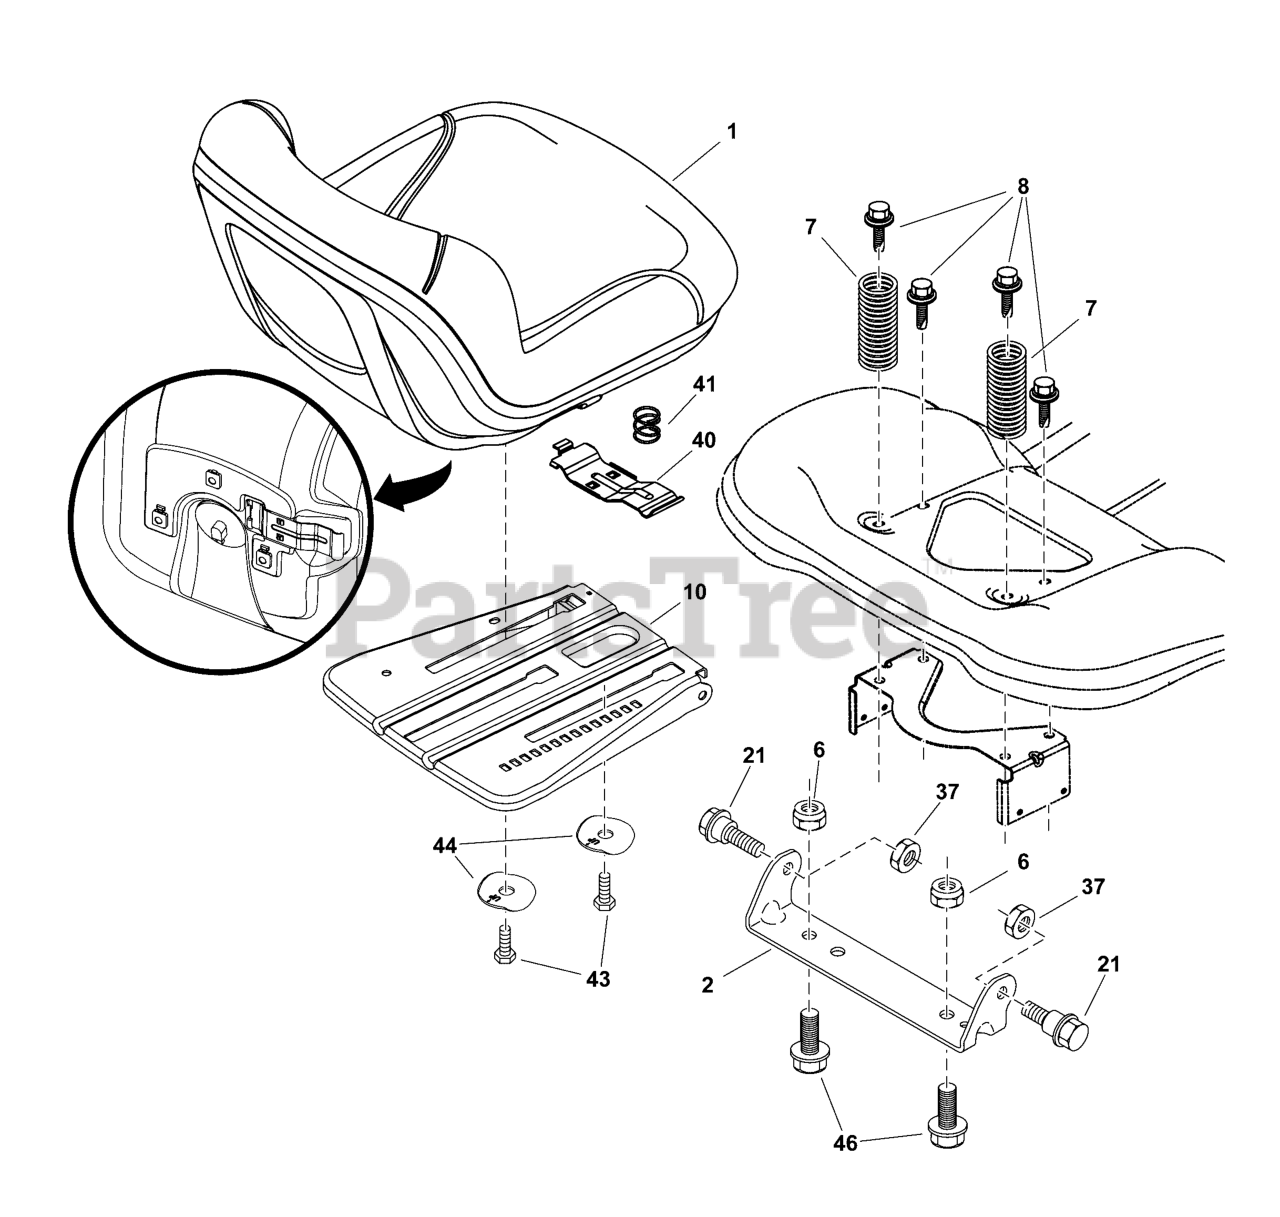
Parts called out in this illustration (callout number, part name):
2	BRACKET, Pivot
6	Nut, Lock w/Ins. 3/8-16 unc
7	SPRING, SEAT CPRSN
8	Bolt 5/16-18 unc x 3/4 w/Sems
10	PAN, Seat
21	BOLT, 5/16-18 x 5/8, Shoulder
37	Nut, Lock 5/16-18 unc
40	Handle Slide Seat
41	Spring Latch Seat
43	Bolt Fin Hex 3/8-16 unc x 3/4
44	WASHER, Winged
46	BOLT, 3/8-16 X 1, 1.25 OD, WSH SEMS
